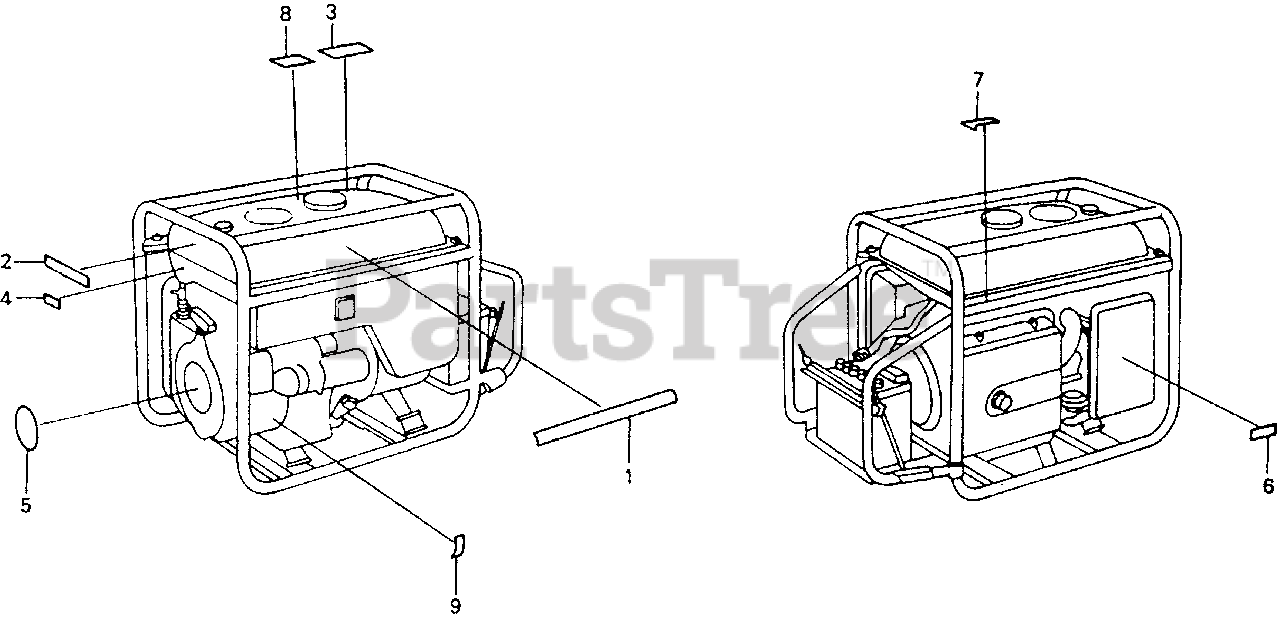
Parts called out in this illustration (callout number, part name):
1	EMBLEM (EM4000)
2	PLATE, CAUTION
3	MARK, CAUTION (ENGLISH/FRENCH)(SPANISH)
4	MARK, CHOKE
5	LABEL, C.D.I. OIL ALERT
6	MARK, AIR CLEANER (ENGLISH)
7	MARK, EX. CAUTION (ENGLISH/FRENCH)
8	MARK, CAUTION (CO)(ENGLISH/FRENCH)(SPANISH)
9	MARK, OIL CAUTION
